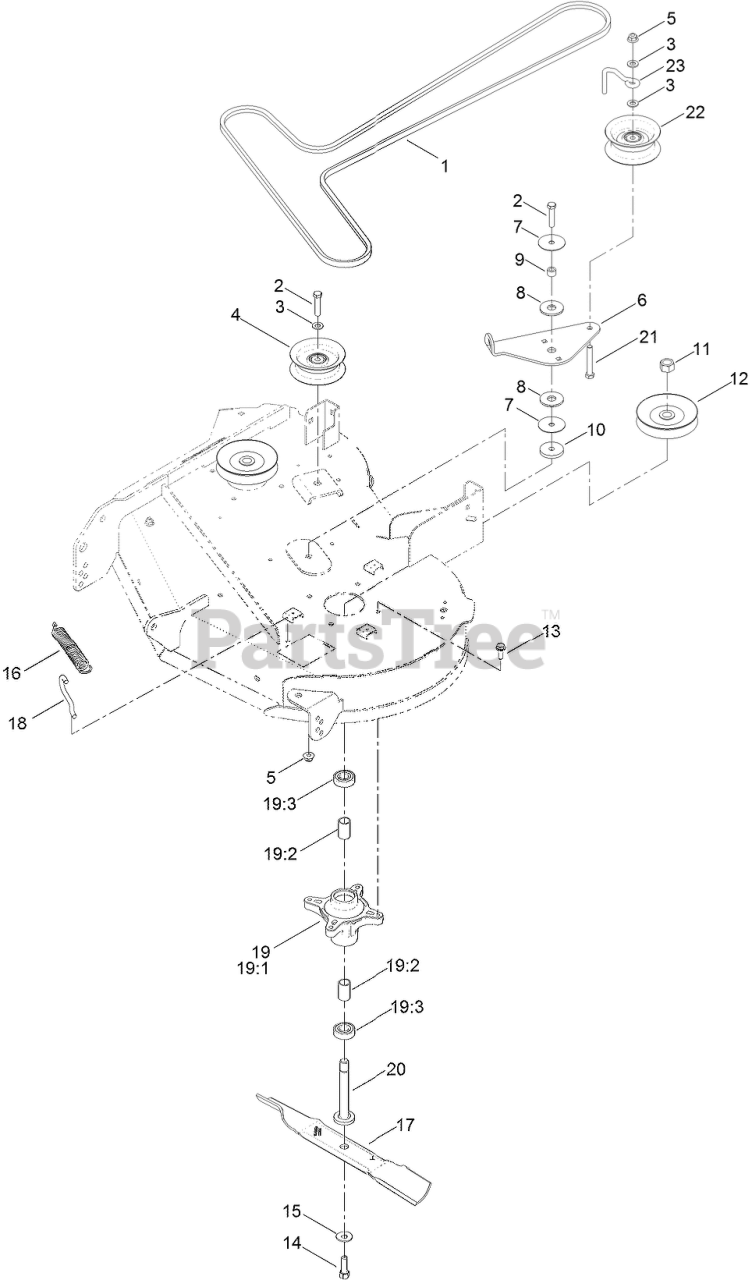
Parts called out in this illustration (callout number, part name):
1	BELT-V
2	SCREW-HH
3	WASHER-FLAT
4	PULLEY-IDLER, FLAT
5	NUT-HF, NI
6	ARM-IDLER
7	WASHER
8	WASHER-FRICTION, COMPOSITE
9	SPACER
10	WASHER-PLAIN
11	NUT-HEX
12	PULLEY ASM
13	SCREW-TAPTITE
14	SCREW-HH
15	WASHER-BELLEVILLE
16	SPRING-EXTENSION
17	BLADE-HI LIFT
18	HOOK-RETURN, SPRING
19	SPINDLE ASM
19:1	SPINDLE
19:2	SPACER
19:3	BEARING-BALL
20	SHAFT-SPINDLE
21	SCREW-HH
22	PULLEY-IDLER, FLAT
23	GUIDE-IDLER, BELT
